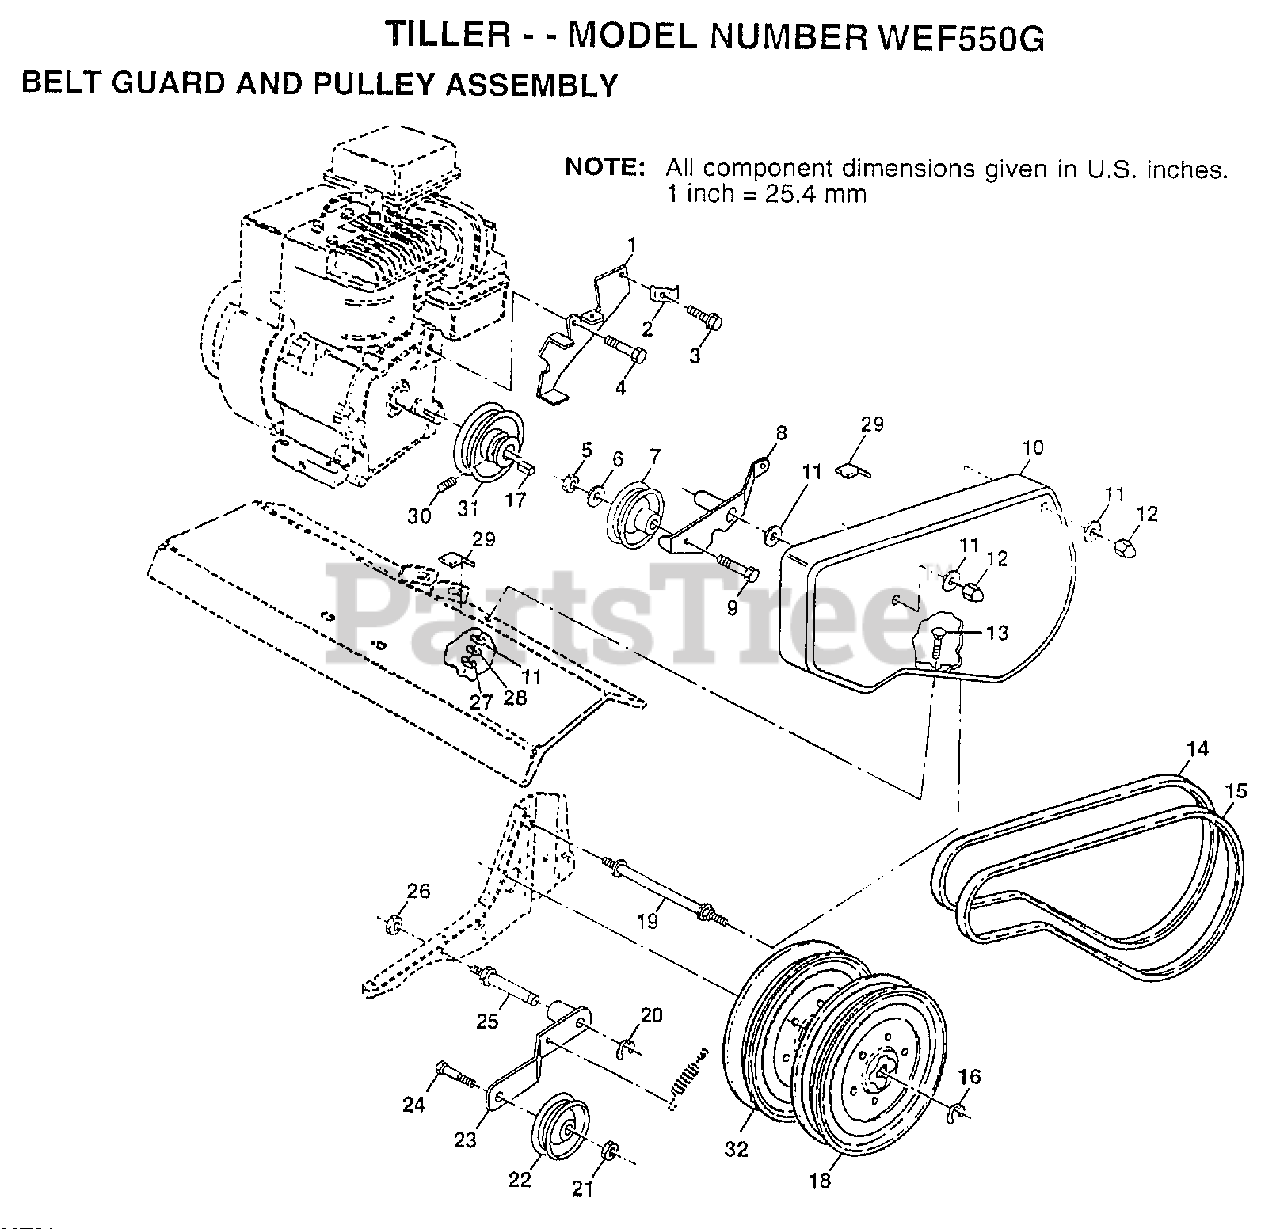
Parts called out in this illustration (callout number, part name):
1	BRKT GUARD BELT
2	PAD IDLER TI
3	ENGINE PULLEY
5	BOLT
7	NUT-CAP TI
8	WASHER
9	GUARD.PNT.BELT
10	BOLT T
11	V BELT STD
12	SET SCREW
14	SHEAVE.TRANS
15	BOLT TI
16	KLIP RING TI
17	NUT
19	IDLER ARM TI
21	SHAFT IDLER TI
22	JAM NUT TI
24	LOCKWASHER
25	NUT
26	WASHER
